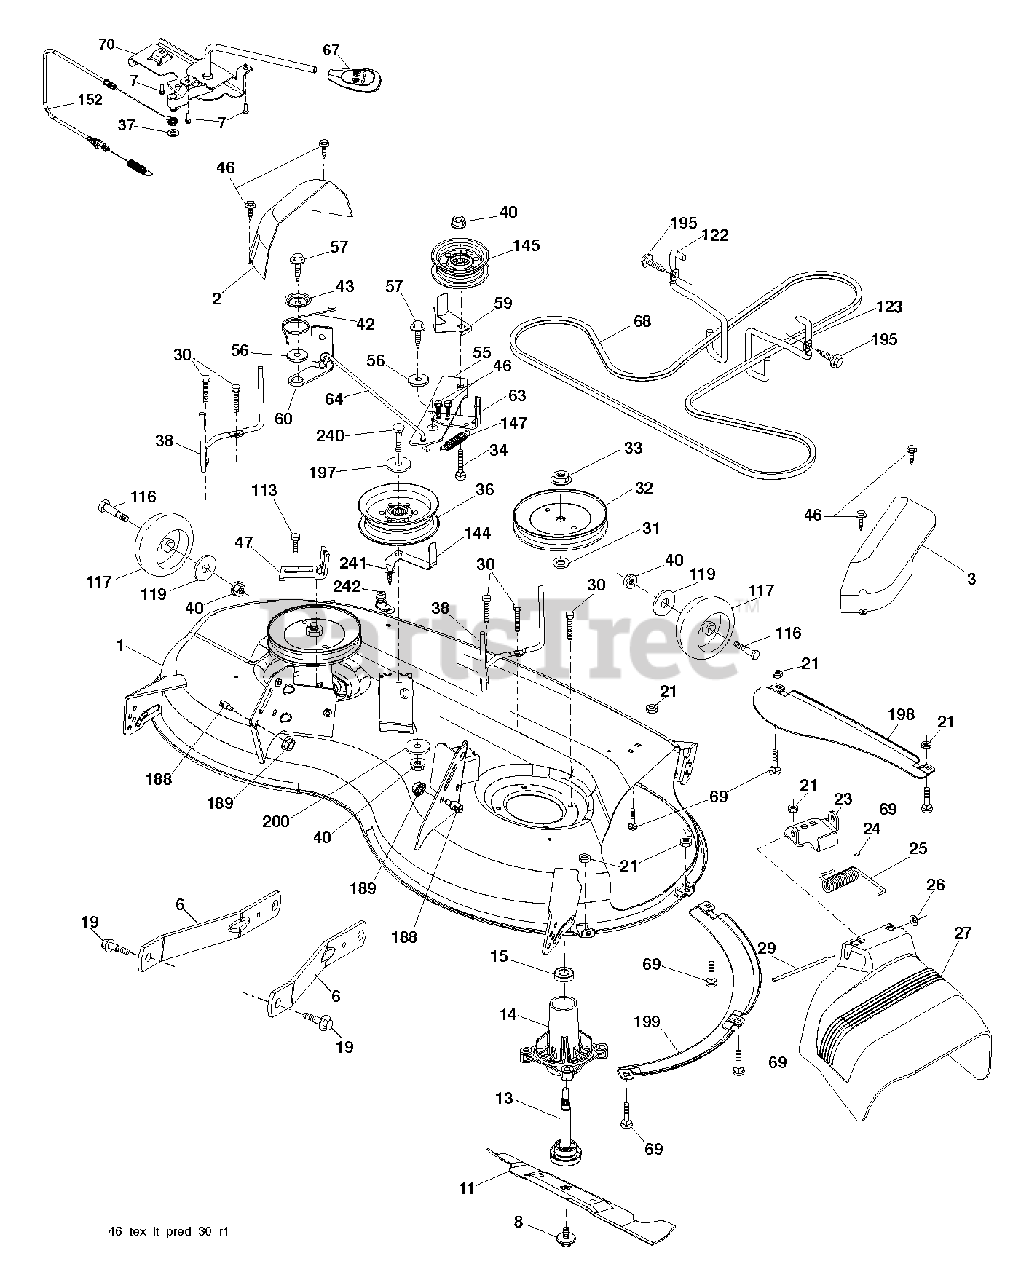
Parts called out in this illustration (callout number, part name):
2	COVER MANDREL LH
3	COVER MANDREL RH
6	ARM.SUSPENSION.MOWER.R
7	SCREW.#10 X 0.750.BOS THREAD
8	BOLT.WASHER.ASM.7/16-2
11	BLADE 46" HI LIFT
13	SHAFT.ASM.MDRL.N/GREASE.38
14	HOUSING MANDREL
15	BEARING
19	BOLT.SHOULDER
23	BRKT.DEFLECTOR.38"2005
24	CAP-SLEEVE LT
25	SPRING.TORSION.DEFLECT
26	NUT PUSH M
27	SHIELD, DEFLECTOR
29	HINGE ROD
30	SCREW, WASHER HEAD
33	NUT.FLANGE.LOCK.TOP
37	WASHER
46	SCREW 1/4-20X5/8
55	IDLER.ARM
56	SPACER.RETAINER
57	SCREW 3/8-16X1
59	GUARD
68	V BELT
69	BOLT
116	BOLT M
117	WHEEL GAGE.HALF.SPOKED
145	PULLEY.IDLER.48"PRIMARY
147	SPRING RETURN
188	STUD.FASTNER.W/D.ANTI-
189	NUT LOCK HEX FLANGE 5/16-18
195	SCREW, 3/8-16X3/4
198	BAFFLE CENTER FRONT
199	BAFFLE FRONT RH
200	WASHER.13/32 X 1 X 1/2.11GUARD
240	BOLT-HEX EAK
242	PORT.WASHOUT
